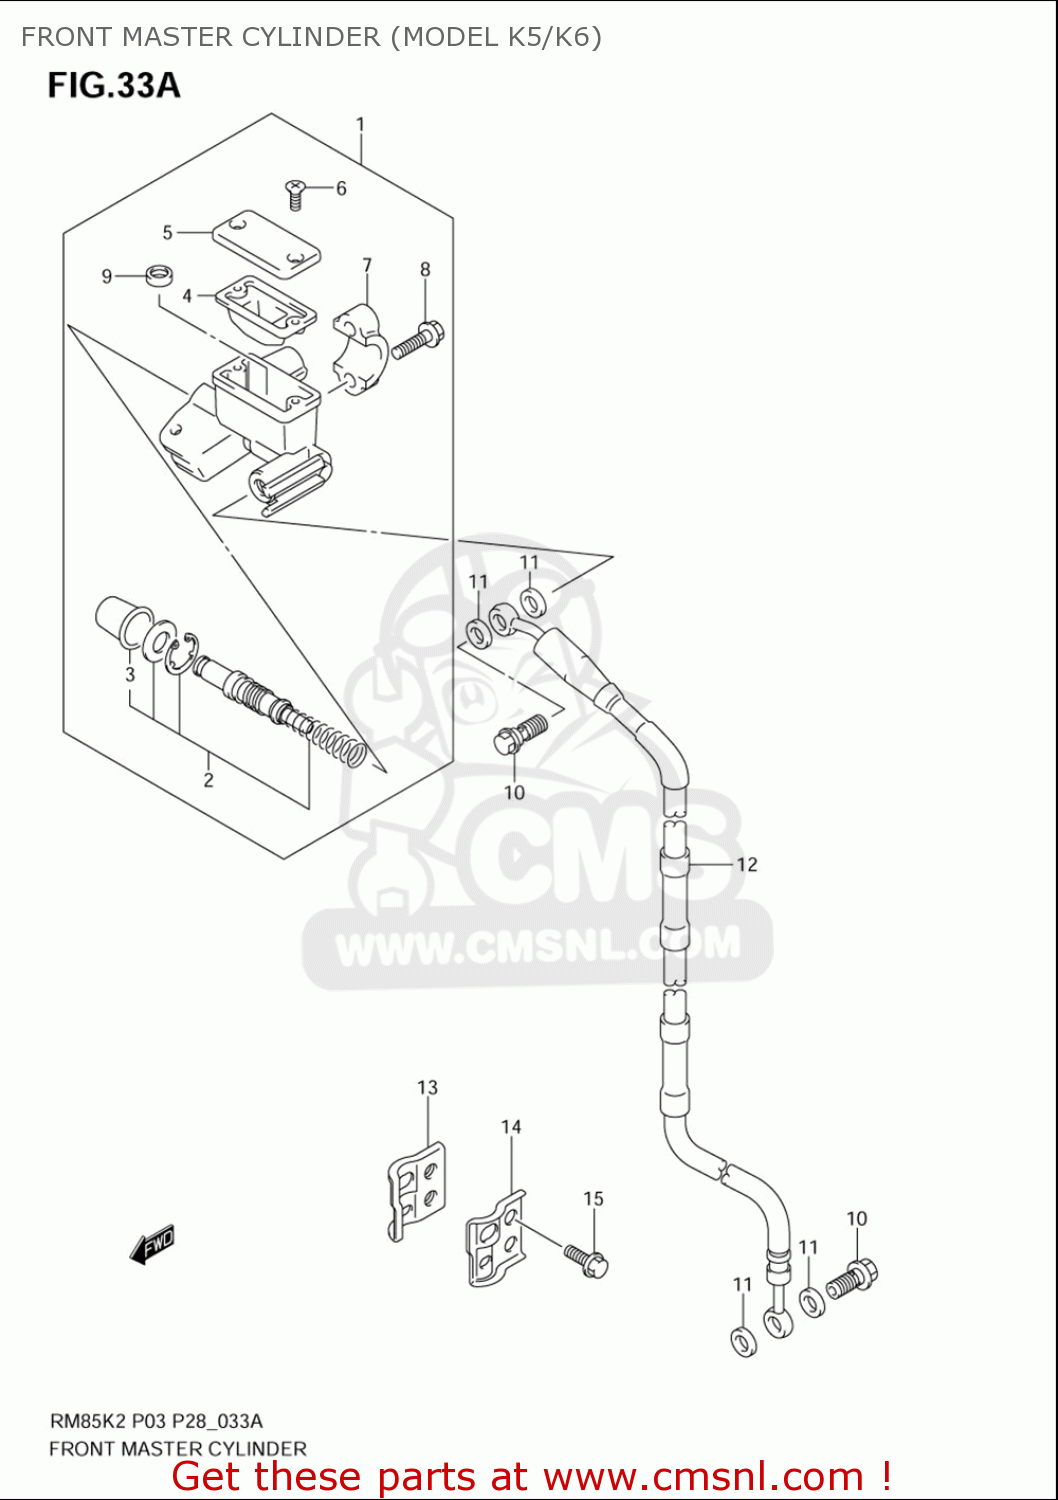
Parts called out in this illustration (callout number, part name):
1	CYLINDER ASSY,FR MASTER
2	PISTON & CUP SET
3	BOOT
4	DIAPHRAGM
5	CAP
6	SCREW
7	HOLDER
8	BOLT
9	SEPARATOR
10	BOLT UNION
11	WASHER(10X15X1.5)
12	HOSE COMP,FRON
13	CLAMP,FR BRAKE HOSE INNER
14	CLAMP,FR BRAKE OUTER
15	BOLT(6X16)
